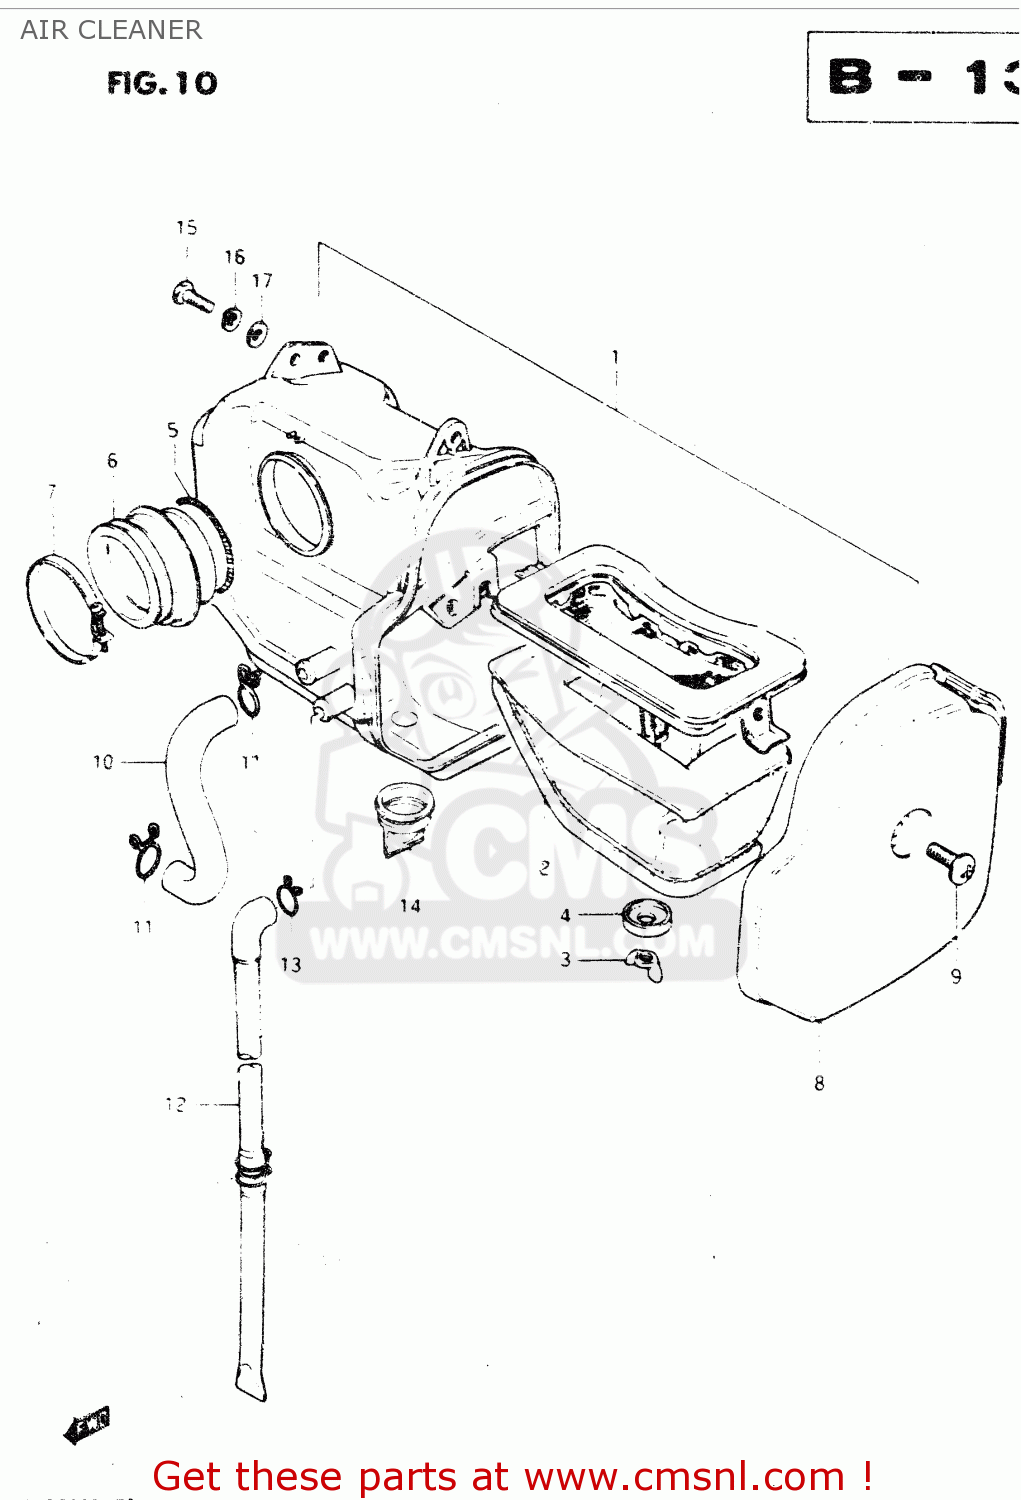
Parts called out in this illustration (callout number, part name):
1	CLEANER ASSEMBLY,AIR
2	ELEMENT,AIR CLEANER
3	NUT
4	WASHER
5	CLAMP,CLEANER SIDE
6	TUBE,AIR CLEANER OUTLET
7	CLAMP
8	CAP
9	SCREW
10	TUBE,BREATHER
11	CLAMP
12	DRAIN TUBE
13	CLAMP
14	HOSE,AIR CLEANER DRAIN
15	BOLT, UPPER
16	LOCK WASHER
17	WASHER
